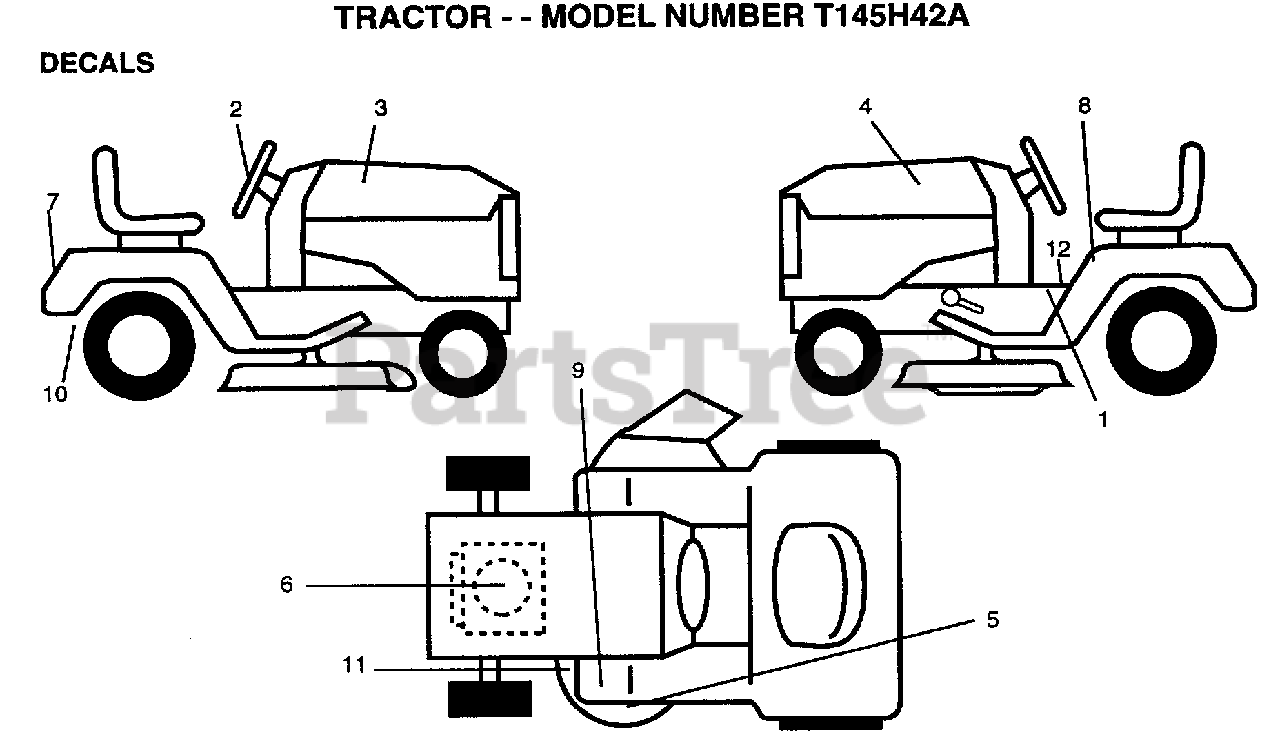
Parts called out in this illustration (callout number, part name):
2	"DECAL,STR WHL T"
3	DECAL.HOOD.RH.CO.
4	DECAL.HOOD.LH.CO.
6	DECAL, ENGINE
7	DECAL.FEND.HYD.CP
8	DECAL
10	DECAL DRAWBAR LH
11	DECAL
12	DECAL SADLE HYDRO
